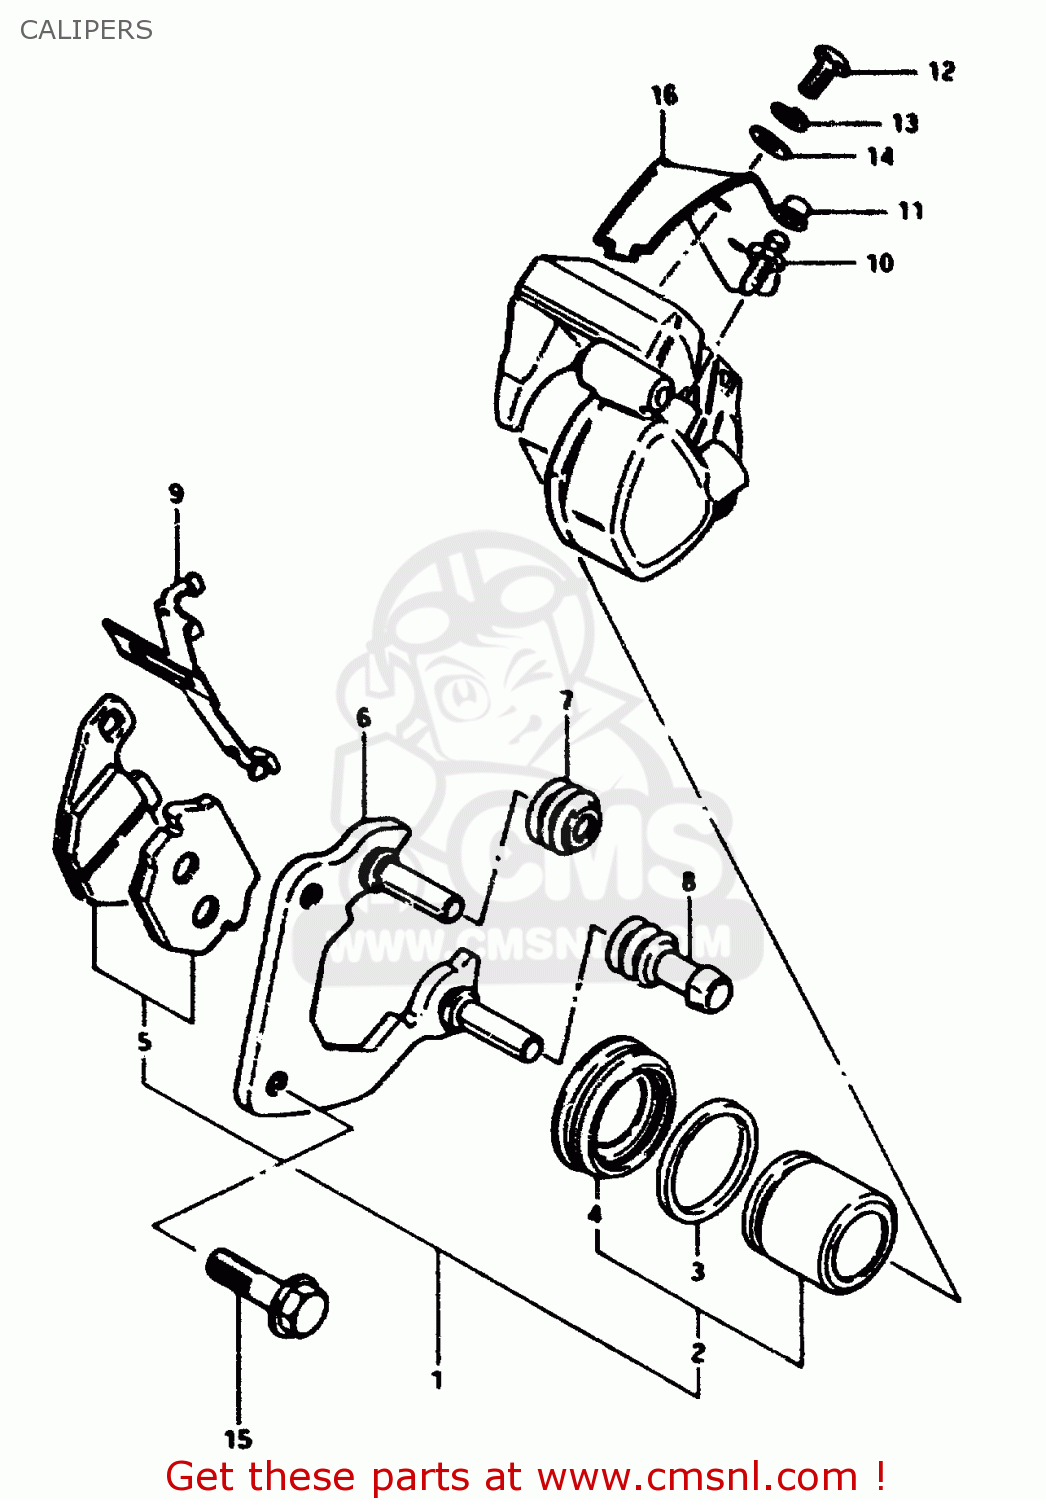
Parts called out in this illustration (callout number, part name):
1	CALIPERS ASSY
2	PISTON SET
3	SEAL,PISTON
4	BOOT,PISTON
5	PAD SET,BRAKE (MCA)
6	CARRIER,CALIPE
7	BOOT,AXLE
8	INSULATOR,AXLE
9	SPRING,PAD
10	BLEEDER
11	CAP,BREATHER
12	SCREW
13	LOCK WASHER
14	WASHER
15	BOLT
16	COVER
